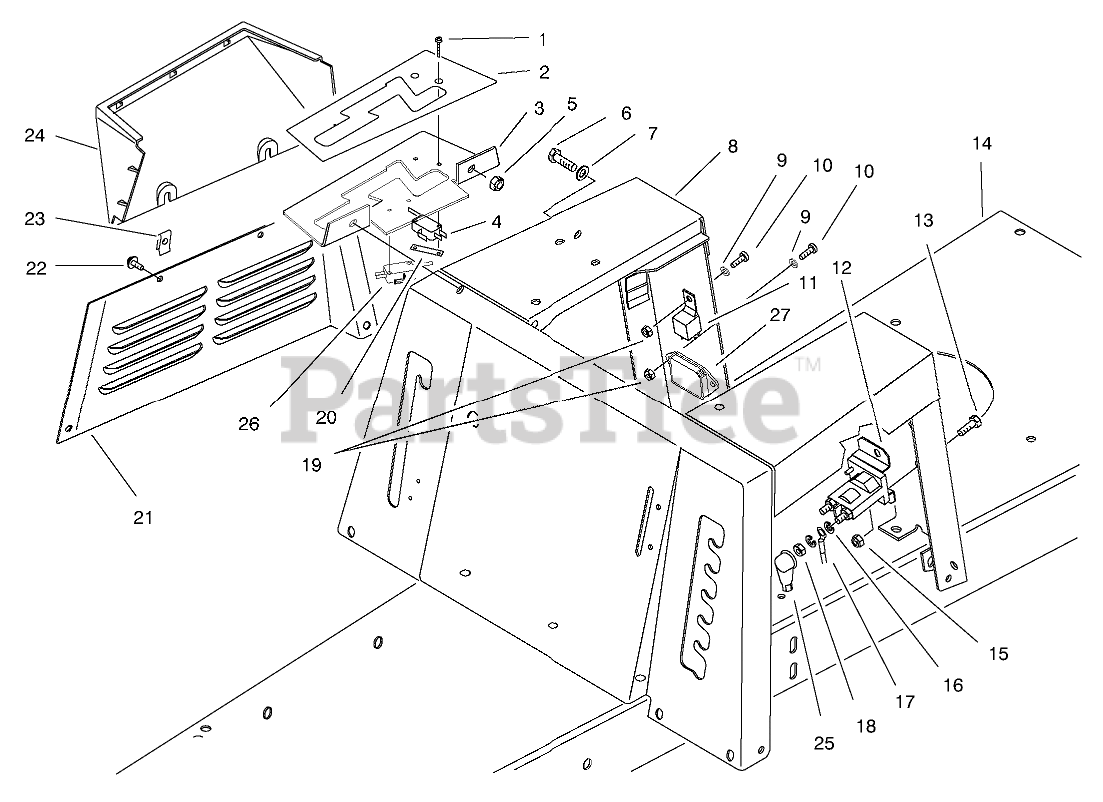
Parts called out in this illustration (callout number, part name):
1	SCREW-HH
2	DECAL - SHIFT PATTERN
3	GATE-SHIFT
4	SWITCH-MICRO
5	NUT-LOCK, NI
6	SCREW-HH
7	WASHER-PLAIN
8	BODY WA-SEAT
9	WASHER-FLAT
11	RELAY
12	SOLENOID
13	SCREW-HH
14	FRAME-MAIN
15	NUT-LOCK, NI
16	WASHER-LOCK
17	WIRE ASM
18	NUT-JAM
19	NUT-LOCK, NI
20	NUT-SPEED
21	PANEL-R/H SEAT BASE
22	SCREW-HWH
23	NUT-CLIP,U
24	COVER-SHIFT GATE
25	BOOT-INSULATOR, TERMINAL
26	SWITCH-MICRO
27	MODULE
